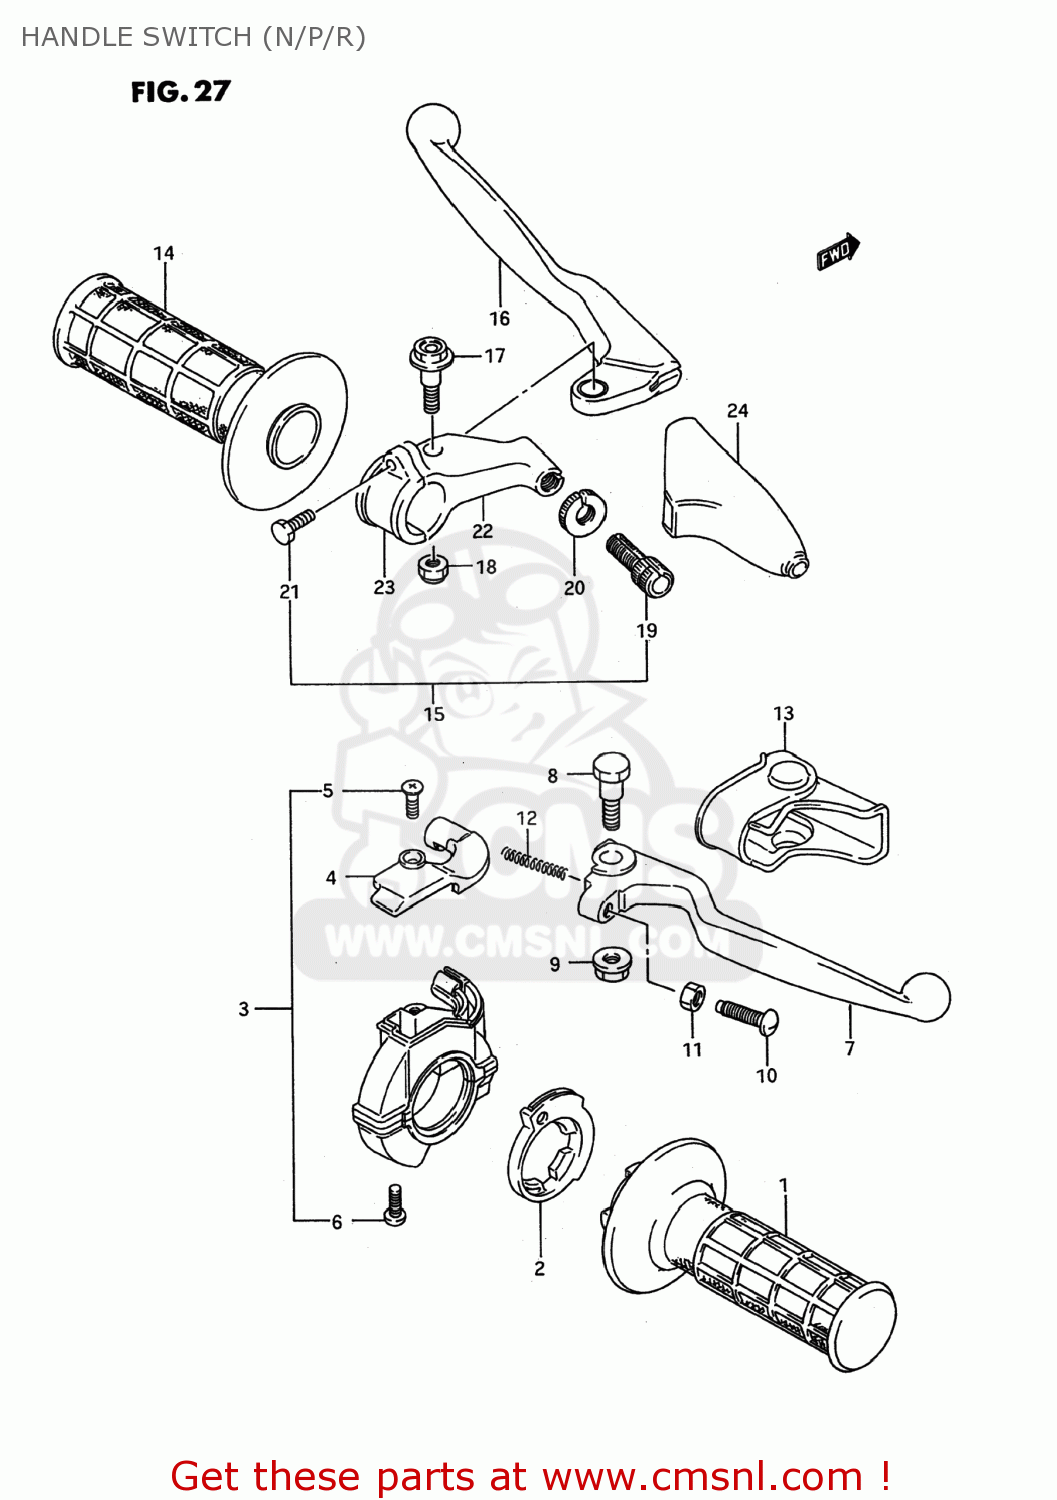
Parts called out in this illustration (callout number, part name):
1	GRIP,THROTTLE
2	ROTOR,THROTTLE GRIP
3	CASE ASSY,THROTTLE
4	COVER,THROTTLE CASE
5	SCREW 4X10
6	SCREW
7	LEVER,BRAKE
8	BOLT,BRAKE LEVER
9	NUT,BRAKE LEVER
10	BOLT,ADJUST
11	NUT ,5MM
12	SPRING,RETURN
13	COVER,BRAKE LEVER
14	GRIP,L
15	LEVER ASSEMBLY
16	LEVER,CLUTCH
17	BOLT,LEVER
18	NUT 6MM
19	ADJUSTER,WIRE
20	NUT,LOCK
21	BOLT
22	HOLDER,CLUTCH LEVER
23	BRACKET,CLUTCH LEVER HOLDER
24	COVER,CLUTCH LEVER
